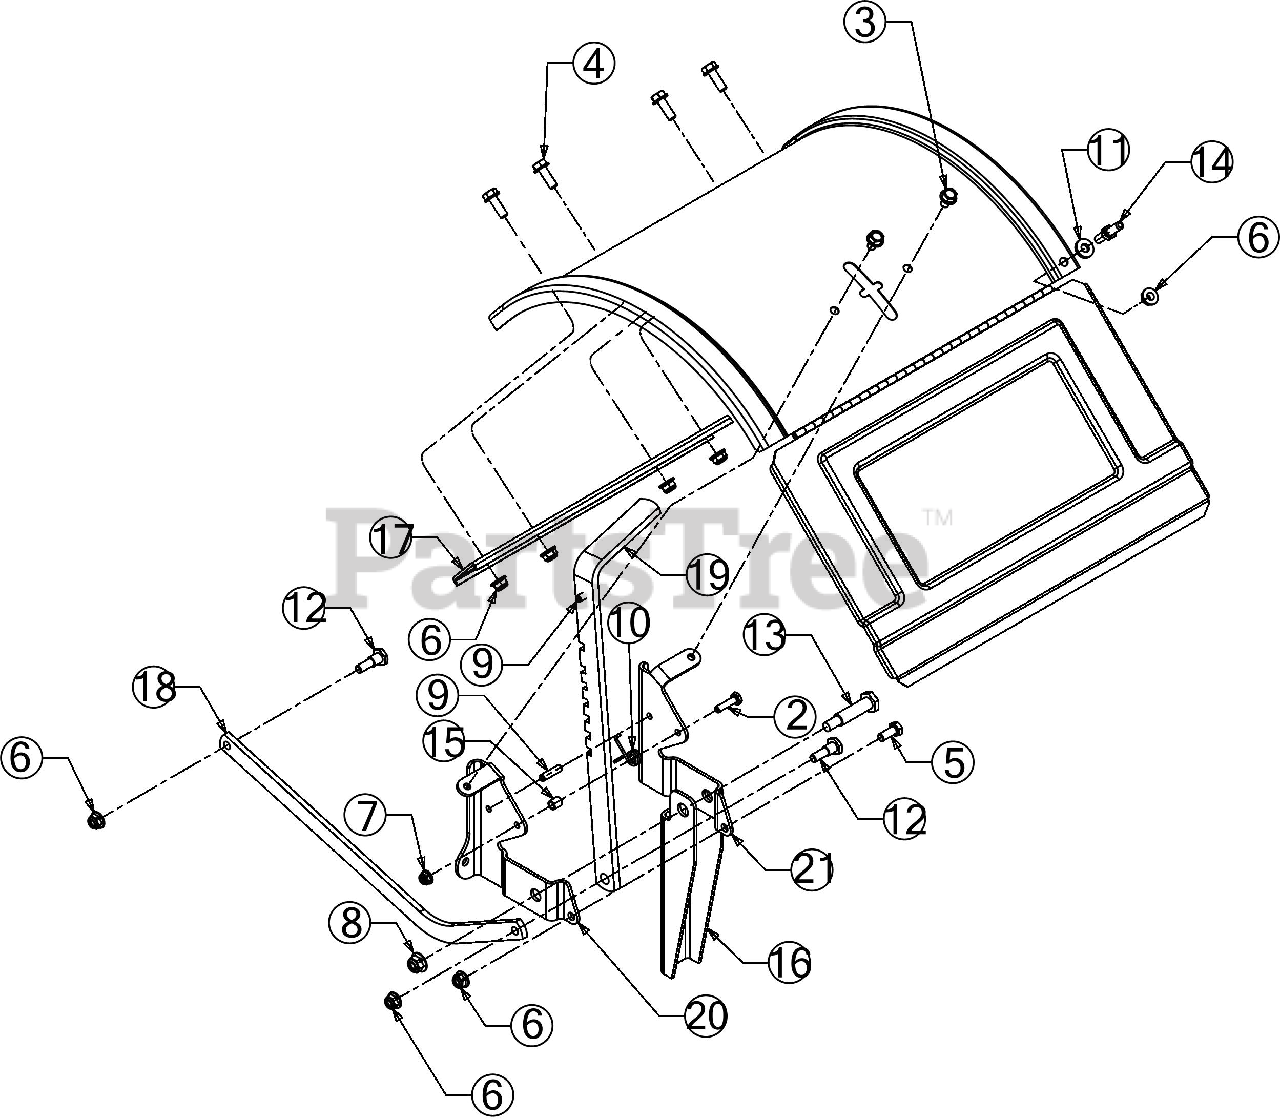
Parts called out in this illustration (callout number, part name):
1	TINE SHIELD ASSEMBLY
2	SCREW 1/4-20 X1.00 GR5
3	SCREW 5/16-18 x .625
4	SCREW 5/16-18 x .875 GR5
5	SCREW 5/16-18 x .75 GR5
6	FLANGE LOCK NUT 5/16-18
7	FLANGE LOCK NUT
9	SPRING PIN 1/4 x 1.00
10	TORSION SPRING
11	FLAT WASHER
12	SHOULDER SCREW
13	SHOULDER BOLT .498 x 1.635:3/8-16
14	SHOULDER SCREW
15	ROUND SPACER
16	REVERSE STOP ARM
17	SUPPORT BRACKET
18	DEPTH DRAG BAR
19	DEPTH ADJUSTMENT BRACKET
20	TAIL BRACKET (LH)
21	TAIL BRACKET (RH)
